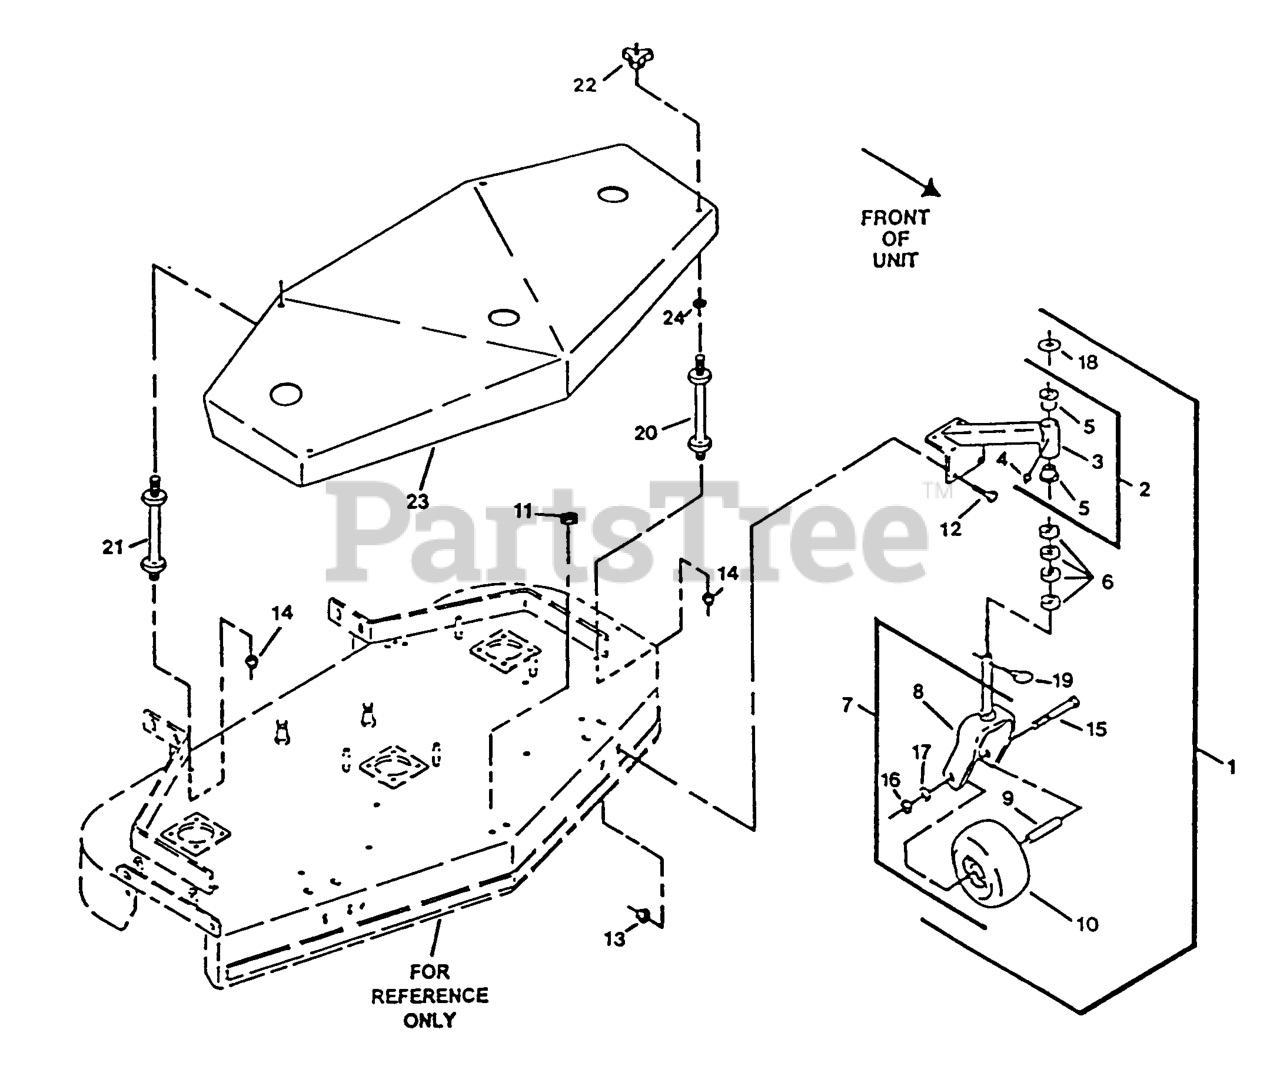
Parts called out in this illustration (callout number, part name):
1	CASTER/MOUNT ASM
2	SUPPORT ASM
5	BEARING-FLANGED
6	SPACER-CASTER
18	WASHER-FLAT
20	STUD-SHIELD, BELT (SHORT)
21	STUD-SHIELD, BELT (LONG)
22	KNOB-3 PRONG
